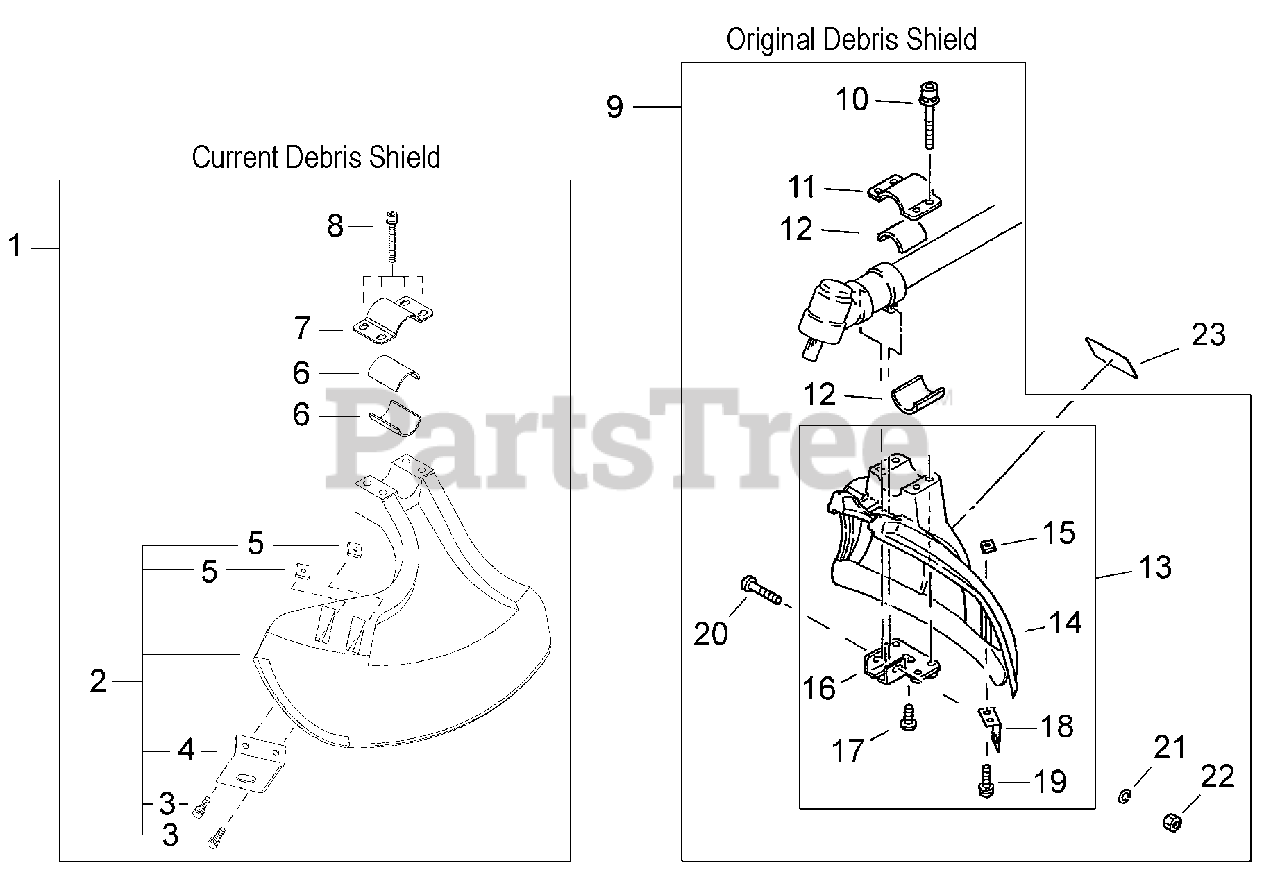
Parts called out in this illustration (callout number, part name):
2	DEBRIS SHIELD ASSY
3	SCREW - 5X16
4	KNIFE, TRIMMER LINE
5	NUT - 5
6	SPACER
7	CLAMP - UPPER
8	SCREW - 5X45
9	DEBRIS SHIELD KIT
10	SCREW - 5X45
11	CLAMP - UPPER
11-1	DEBRIS SHIELD KIT
12	SPACER
13	DEBRIS SHIELD KIT
14	SHIELD, DEBRIS
15	NUT - 5
16	CLAMP - LOWER
17	SCREW
18	KNIFE, TRIMMER LINE
19	SCREW - 5X16
20	SCREW - 5X35
21	WASHER - 5
22	NUT - 5
23	LABEL - MODEL
